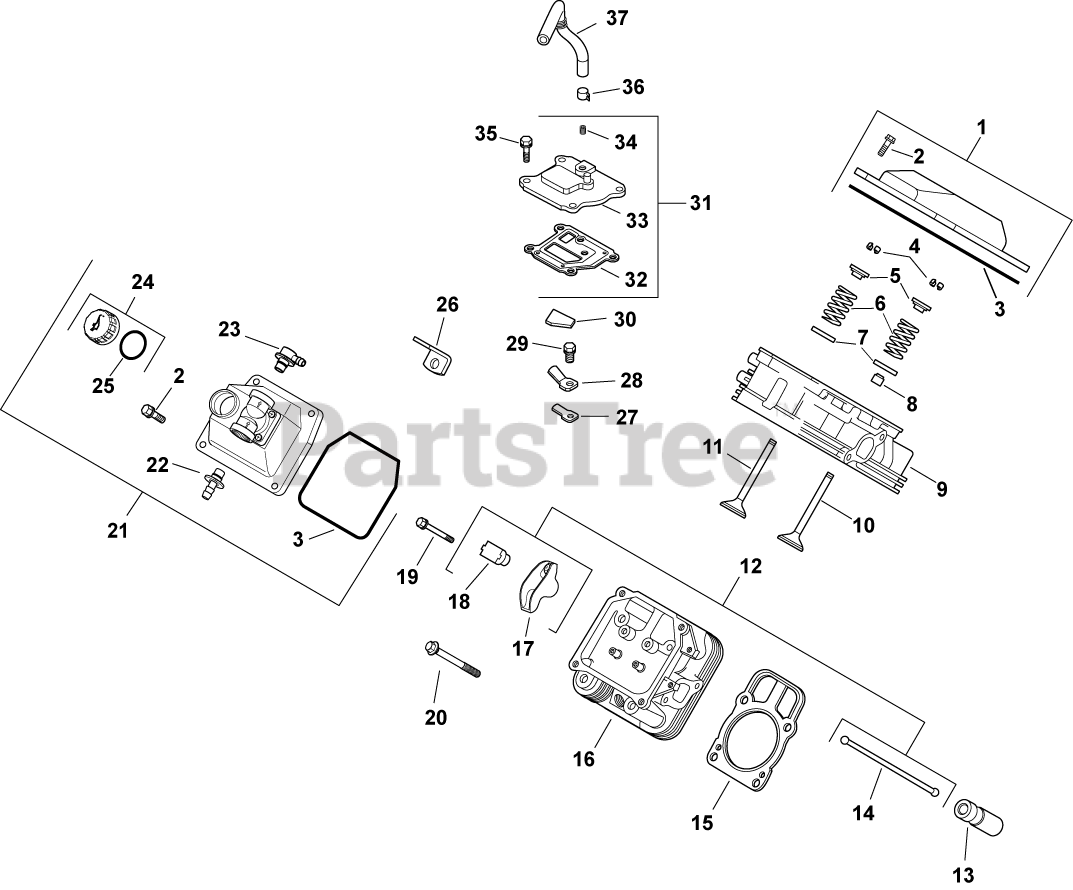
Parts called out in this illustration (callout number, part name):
1	KIT, VALVE COVER-PLAIN
2	SCREW, FLG M6X1.0X30
3	O-RING (YELLOW), VALVE COVER
4	KIT, RETAINER
5	RETAINER, VALVE SPRING - USE 25 173 28-S
6	SPRING, VALVE
7	RETAINER, SPRING
8	SEAL, VALVE STEM - (#2503214S)
9	HEAD, ASSEM CYLINDER #1 -USE 24 318 107-
10	VALVE, INTAKE (STD)
11	VALVE, EXHAUST (STD) - USE 32 016 01-S
12	KIT, VALVE TRAIN
13	LIFTER, HYDRAULIC VALVE-USE 25 351 10-S
14	ROD, PUSH
15	KIT, CYL HEAD GASKET (C17-22)
16	HEAD, ASSEM CYLINDER #2 -USE 24 318 115-
17	ARM, ROCKER
18	PIVOT, ROCKER ARM
19	SCREW, FLG M6X1.0X34
20	SCREW - USE 62 086 08-S
21	KIT, VALVE COVER-FUEL PUMP
22	KIT, STRAIGHT FITTING
23	KIT, 90 DEG. FITTING
24	CAP ASSY, OIL FILL (YELLOW)
25	O-RING-USE 24 153 32-S
27	REED, BREATHER
28	RETAINER, REED
29	SCREW, FLG THD FRM M5X.8X10
30	FILTER, BREATHER
31	KIT, BREATHER ASSEMBLY
32	GASKET, BREATHER-USE 24 041 67-S
33	COVER, BREATHER -USE 24 033 01-S
34	PLUG, CTSK PIPE 1/8"
35	SCREW,FLG THD FRM M6X1.0X20-(#25086396S)
36	CLAMP, BAND SPRING HOSE-(#2523737S)
37	HOSE, BREATHER
2401602-S	VALVE, EXHAUST (.25)
2401702-S	VALVE, INTAKE (.25)
2544501-S	STRAP, LIFTING-USE 25 445 03-S
24755147-S	KIT, CYLINDER HEAD HARDWARE
